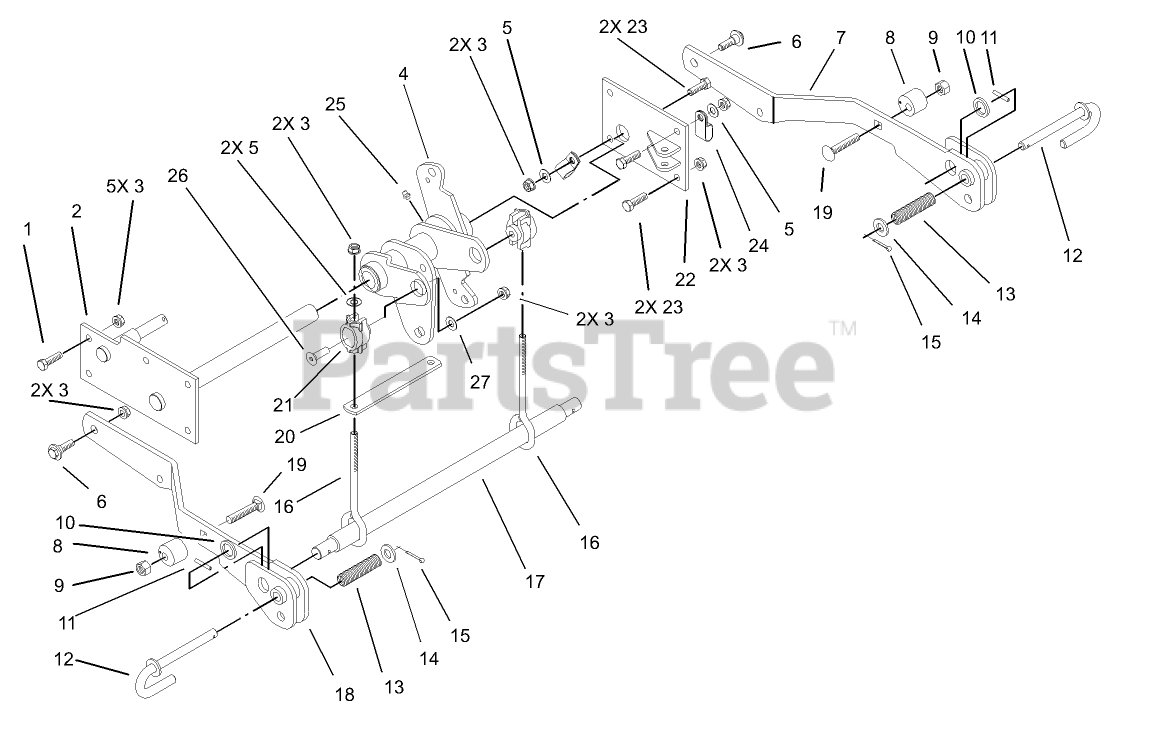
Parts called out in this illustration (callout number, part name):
1	SCREW-HH
2	SUPPORT-LIFT, DECK
3	NUT-LOCK, NI
4	BELLCRANK AND BUSHING ASM
5	WASHER-FLAT
6	SCREW-SHOULDER, HWH
7	ARM-LIFT, LH
8	STOP-LIFT, ADJ.
9	NUT-LOCK, NI
10	WASHER-FLAT
11	PIN-ROLL
12	PIN - J
13	SPRING-COMPRESSION
14	WASHER-FLAT
15	PIN-COTTER
16	ROD-LIFT
17	BAR-LIFT
18	ARM-LIFT, RH
19	SCREW-CARR
21	SLEEVE-LIFT
22	PLATE-LH SUPPORT
23	SCREW-HH
24	CLAMP-TUBE
25	FITTING-GREASE
26	SCREW-HSFH
27	WASHER-FLAT
